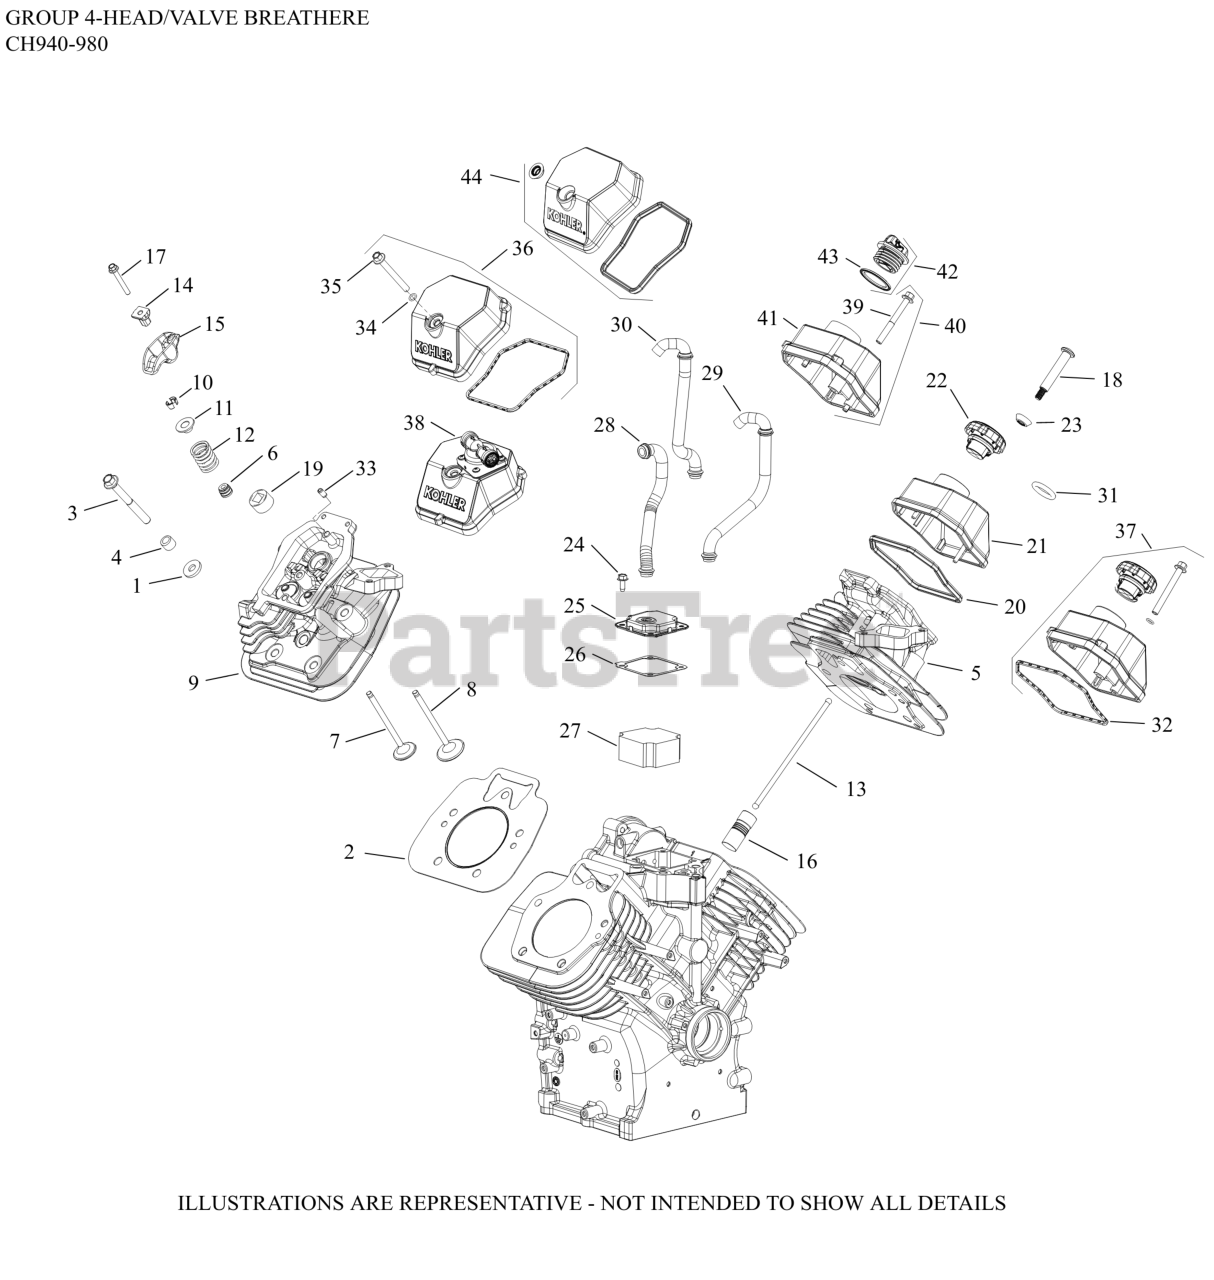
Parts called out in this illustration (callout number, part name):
1	WASHER, FLAT 13/32"
2	KIT, CYLINDER HEAD GASKET
3	SCREW, FLG M10X1.5X90
5	KIT, HEAD CYLINDER #1-(#6281801S)
6	SEAL, VALVE BAND
7	VALVE, EXHAUST
8	VALVE, INTAKE
9	KIT, HEAD CYLINDER #2
10	KIT, RETAINER
11	CAP, VALVE SPRING
12	SPRING, VALVE
13	ROD, PUSH
14	PIVOT, ROCKER ARM
15	ARM, ROCKER
16	LIFTER, VALVE HYDRAULIC-USE 25 351 11-S
17	SCREW, HEX FLANGE (SILVER) M6X1.0X45
18	SCREW, SHOULDER
19	PLUG, PIPE 3/4 NPTF SQUARE
20	SEAL, VALVE COVER
21	KIT, COVER, VALVE (OIL FILL)
22	CAP ASSEMBLY
23	GROMMET, VALVE COVER SCREW
24	SCREW, THREAD FORMING
25	KIT, BREATHER ASSEMBLY
26	GASKET, BREATHER
27	FILTER, BREATHER
28	HOSE, BREATHER H/S
